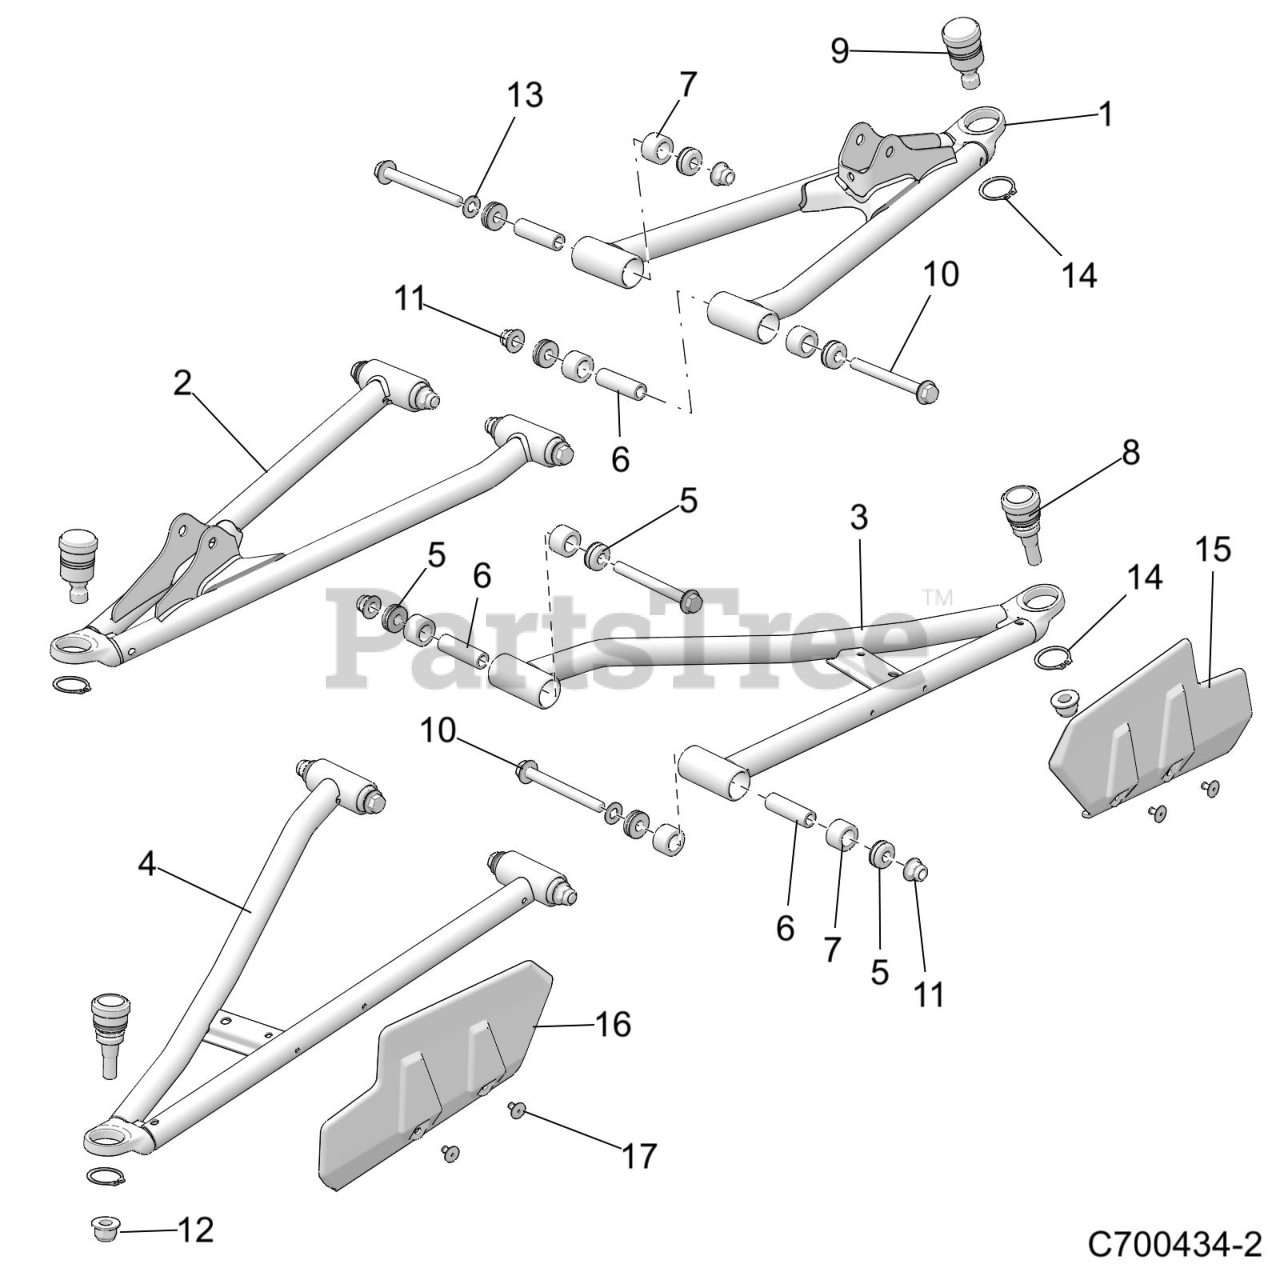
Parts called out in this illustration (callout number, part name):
1	WELD-A-ARM,FR,UPR,LH,BLK
2	WELD-A-ARM,FR,UPR,RH,BLK
3	WELD-A-ARM,FRT,LWR,LH,M.BLK
4	WELD-A-ARM,FRT,LWR,RH,M.BLK
5	ASM-PIVOT CAP,SEALED,M10
6	SHAFT-PIVOT,SHORT,M10
7	BUSHING-STANDARD,SUSP,M10
8	BALL-JOINT,M12X1.50,TAPERED
9	BALL-JOINT,10MM STUD
10	SCR-HXFL-M10X1.25X95 10.9 ZOD
11	NUT-M10X1.25,FLG,NYLOC-OLIVE D
12	NUT-M12X1.5,FLG,NYLOC-OLIVE D
13	WASHER,3/8 FW
14	RING-RETAINER,EXTERNAL,1.188
15	SHIELD-CV,FRONT,LH,BLK
16	SHIELD-CV,FRONT,RH,BLK
17	RIVET(50) *
